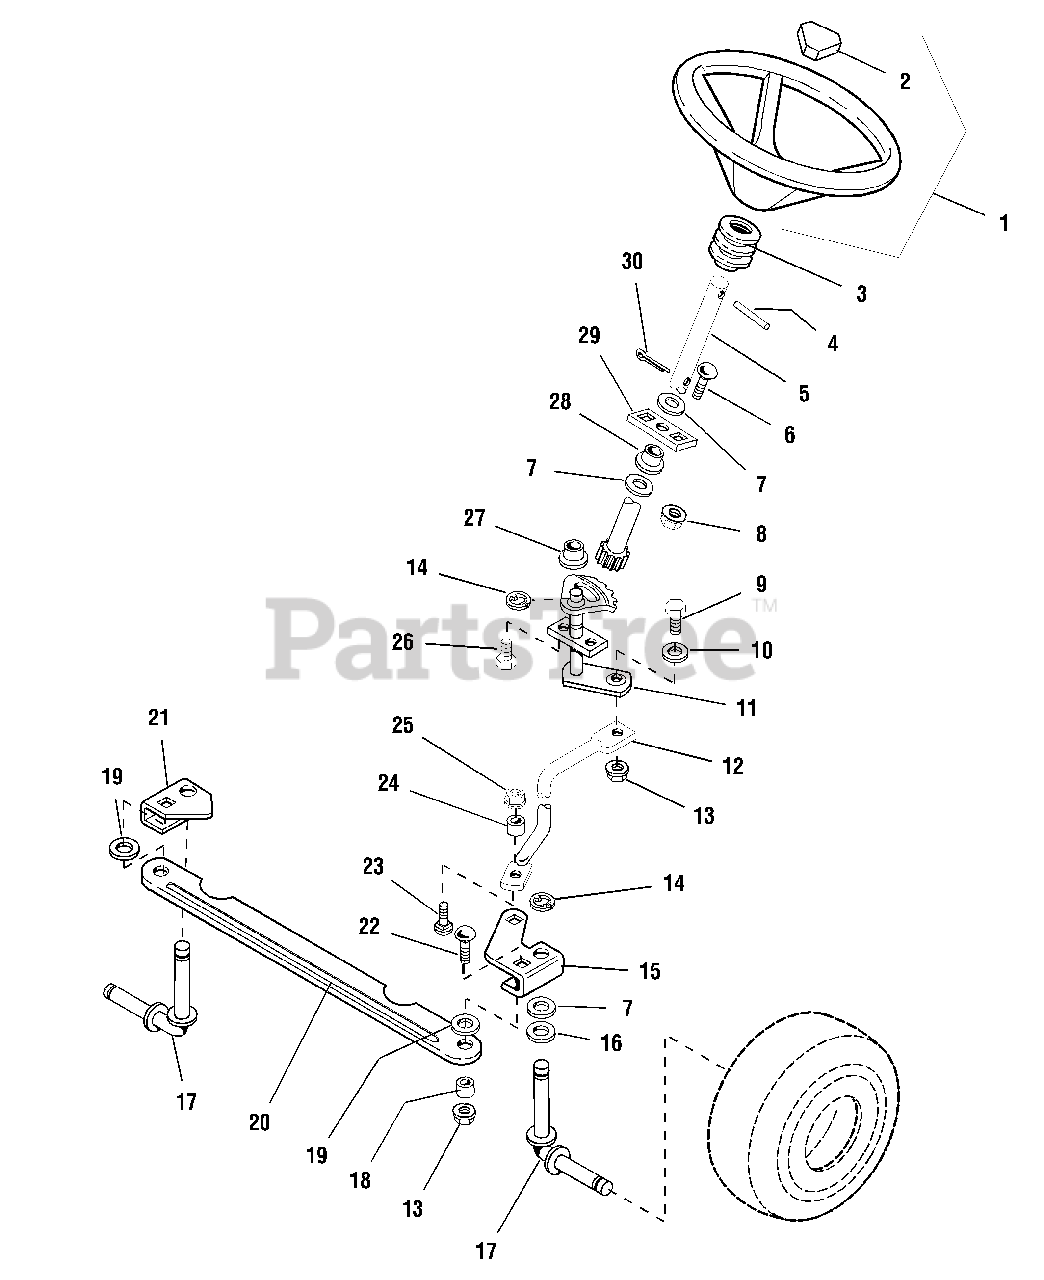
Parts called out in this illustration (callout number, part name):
1	STEERING WHEEL ASSY.,
2	CAP, Steering Wheel
4	PIN, Spring, 5/16 x 2-1/2
5	SHAFT ASSY., Steering
6	CARRIAGE BOLT, 3/8-16 x 1
7	WASHER
8	NUT, Flange Lock ,Whiz, 3/8-16
9	CAPSCREW, 3/8-16 x 1-3/8
11	STEERING GEAR ASSY.
13	NUT, Hex, Flange Lock. 3/8-16
15	ARM, Steering, LH
17	SPINDLE ASSY.
19	WASHER, 5/8
21	ARM, Steering, RH
22	CARRIAGE BOLT, 3/8-16 x 1-1/4
23	CARRIAGE BOLT, 5/16-18 x 1
25	NUT, Hex, Flange Lock, 5/16-18
26	SCREW, Taptite, 5/16-18 x 3/4
29	PLATE, Steering, Mounting
30	PIN, Cotter, 3/16 x 1-1/4
